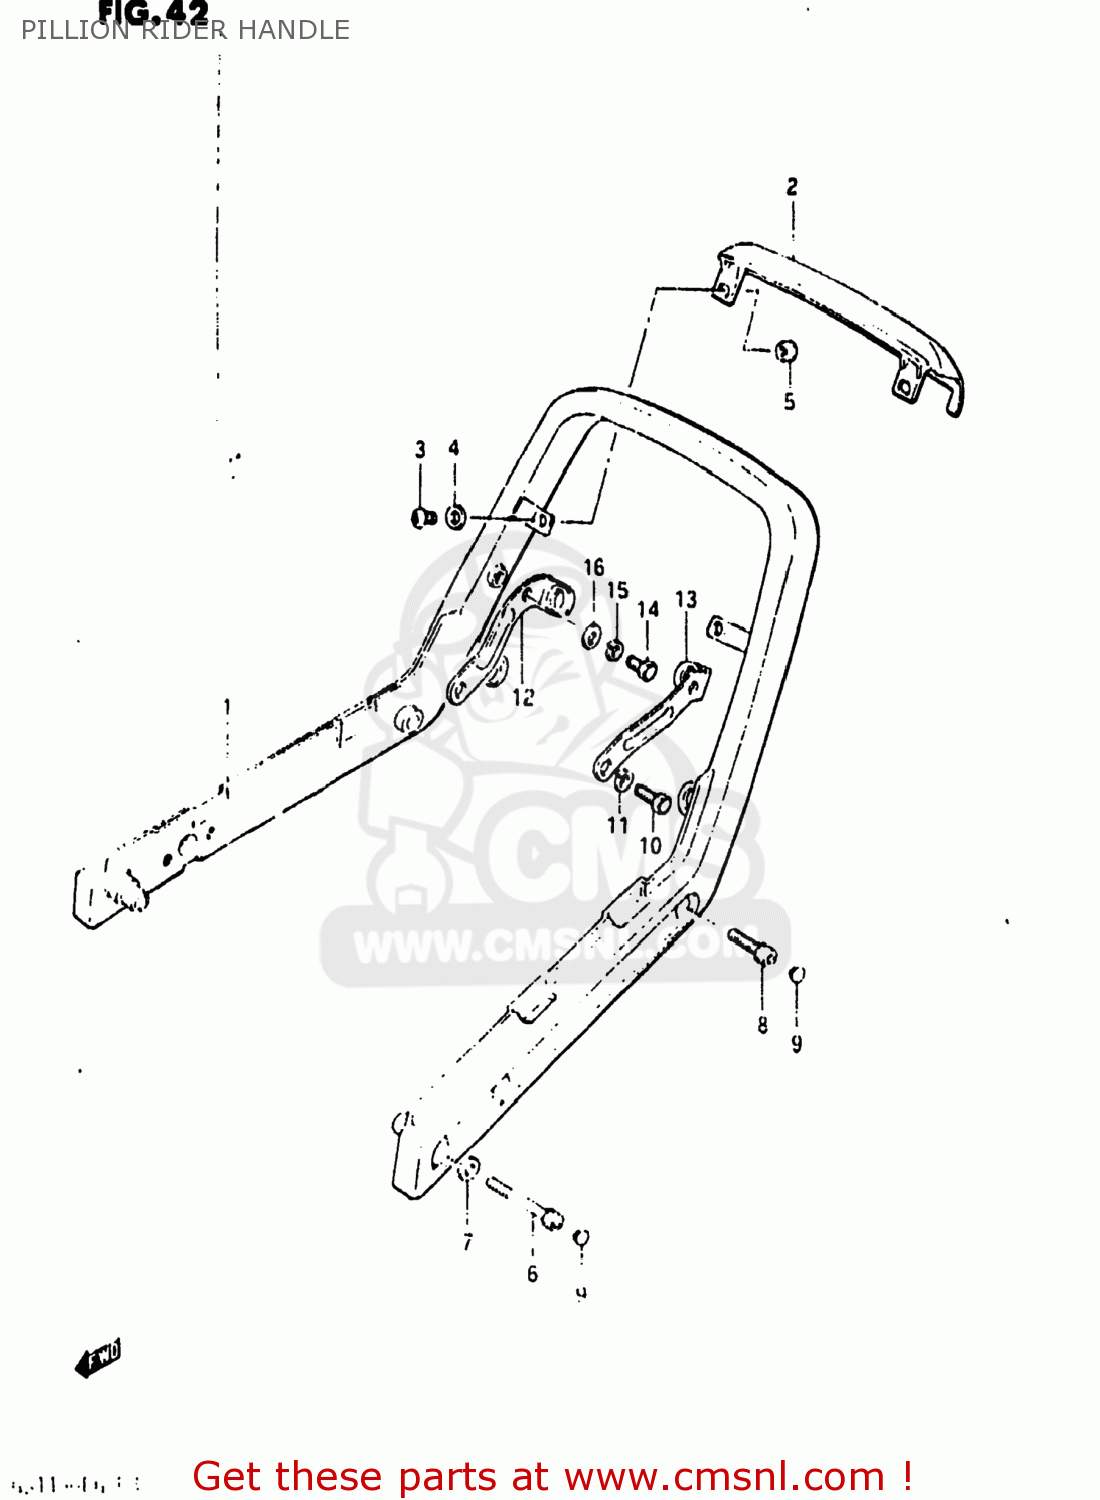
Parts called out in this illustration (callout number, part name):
1	HANDLE,PILLION RIDER
2	COVER,PILLION RIDER HANDLE
3	SCREW
4	WASHER
5	NUT
6	BOLT
7	WASHER
8	BOLT
9	CAP(OD:10)
10	BOLT, 8X1.25X1
11	WASHER,LOCK,8.
12	PLATE,PILLION RIDER HANDLE
13	PLATE,PILLION RIDER HANDLE
14	BOLT 8X12
15	WASHER,LOCK,8.
16	WASHER 8MM
